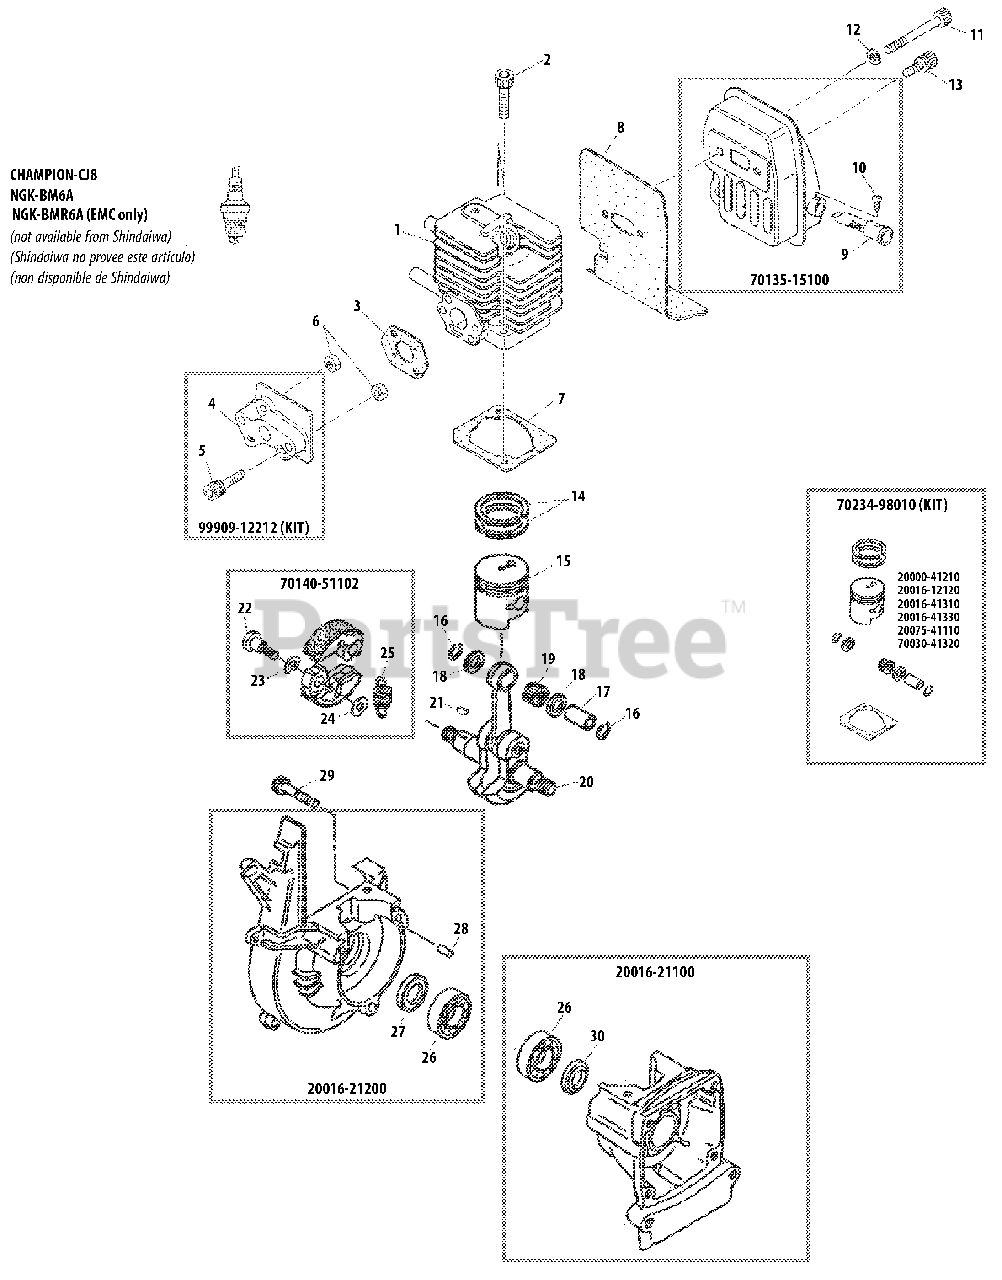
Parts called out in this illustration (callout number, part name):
1	CYLINDER
2	SCREW - 5X25
3	GASKET
4	INSULATOR
5	SCREW - 5X30
6	NUT
7	GASKET, CYLINDER
8	SHIELD, EXHAUST
9	SCREEN, SPARK ARRESTOR
10	SCREW - 3X6
11	SCREW - 5X50
12	WASHER - 5
13	SCREW - 5X12
14	RING, PISTON
15	PISTON
16	RING, RETAINING
17	PIN, PISTON
18	WASHER, THRUST
19	BEARING, NEEDLE
20	CRANKSHAFT ASSY
21	KEY - 3X10
22	BOLT, CLUTCH
23	WASHER - SPRING
24	WASHER - 6
25	SPRING, CLUTCH
26	BEARING, BALL - 6001C3
27	SEAL, OIL - 12
28	PIN - LOCATING
29	SCREW - 5X25
30	SEAL, OIL
20016-21100	CRANKCASE ASSY - REAR
20016-21200	CRANKCASE ASSY - FRONT
70135-15100	MUFFLER ASSY
70140-51102	CLUTCH ASSY
70234-98010	PISTON ASSY
99909-12212	INSULATOR ASSY
